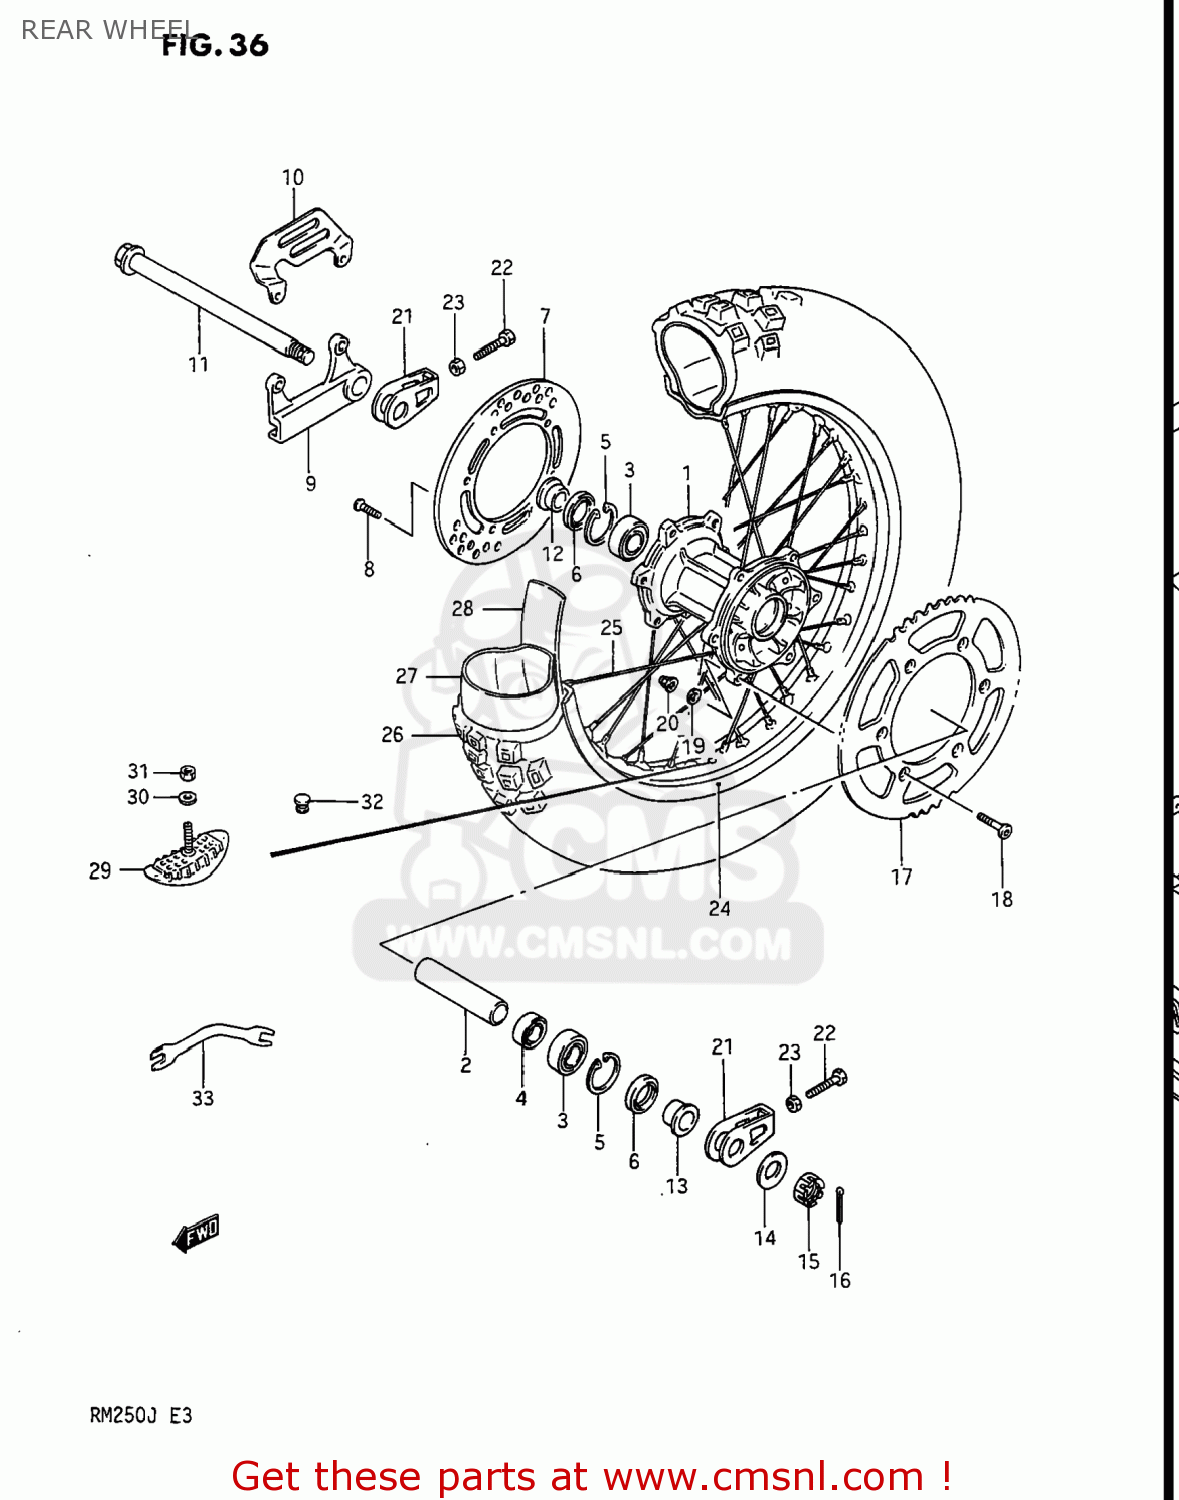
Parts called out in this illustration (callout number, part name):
1	HUB,REAR WHEEL
2	SPACER,RR HUB BEARING
3	BEARING
4	BALL BEARING
5	CIRCLIP,14MM
6	OIL SEAL
7	DISC,REAR BRAKE
8	SCREW
9	BRACKET,REAR CALIPER
10	GUARD,REAR CALIPER
11	AXLE,RR
12	SPACER,RR AXLE,R
13	SPACER,REAR AXLE,LEFT
14	WASHER (19X32X3.2)
15	NUT 18MM
16	PIN,COTTER
17	SPROCKET,REAR
18	SCREW(8X33.5)
19	WASHER
20	NUT
21	ADJUSTER COMP,CHAIN
22	BOLT L:50
23	NUT
24	RIM,REAR WHEEL
25	SPOKE ASSY,RR WHEEL
26	TIRE,REAR
27	TUBE,INNER
28	PROTECTOR,WHEEL,INNER
29	STOPPER,BEAD
30	WASHER
31	NUT 8MM
32	CAP(OD:12)
33	SPANNER,OPEN
